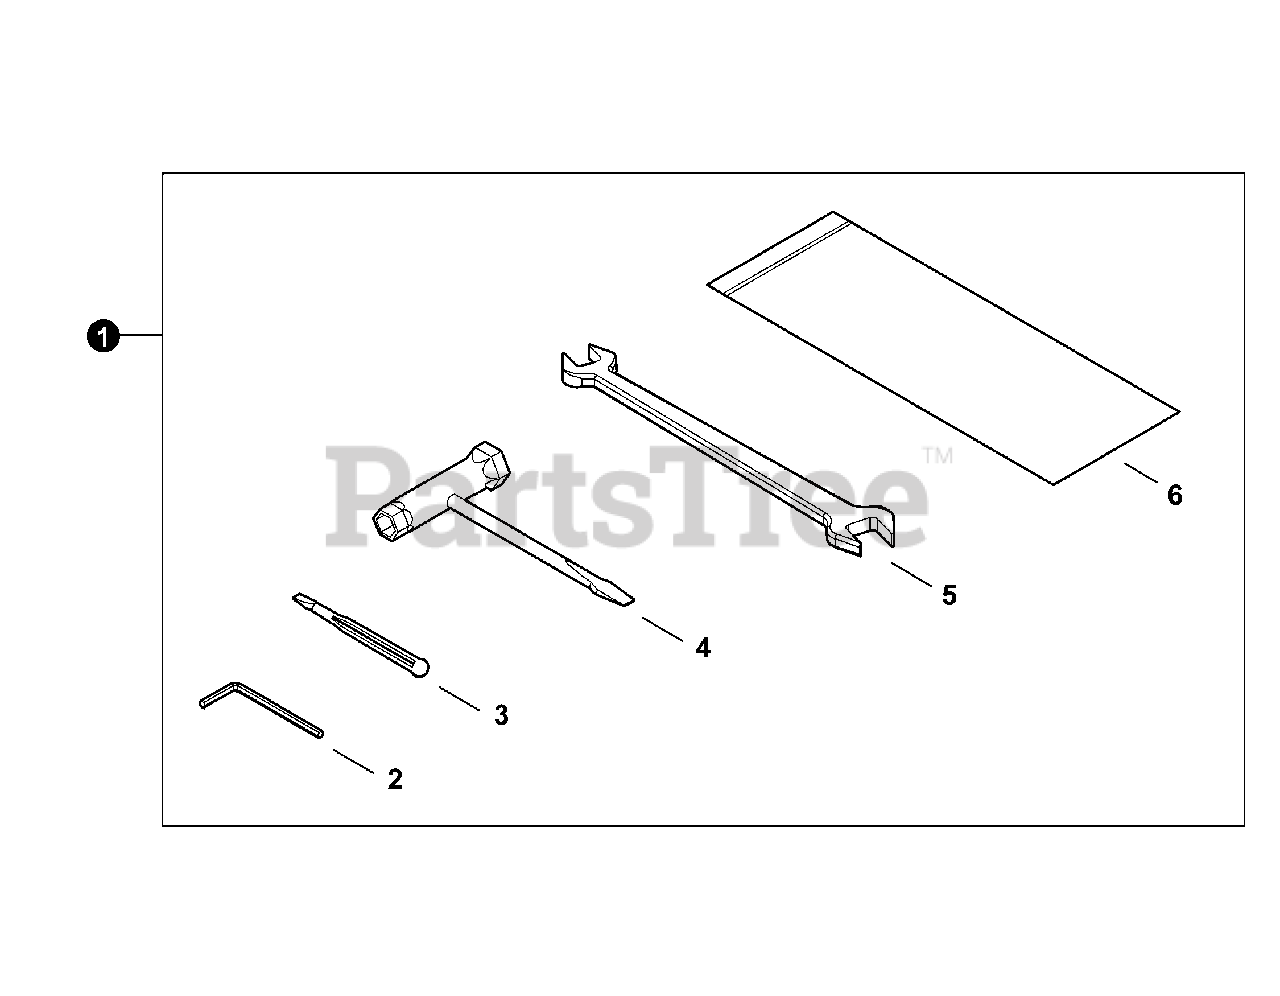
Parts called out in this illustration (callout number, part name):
1	TOOL KIT, SERVICE
2	WRENCH, ALLEN 4 MM
3	SCREWDRIVER, PLASTIC
4	T-WRENCH 13×19 MM
5	SPANNER 8×10
6	BAG, TOOL
